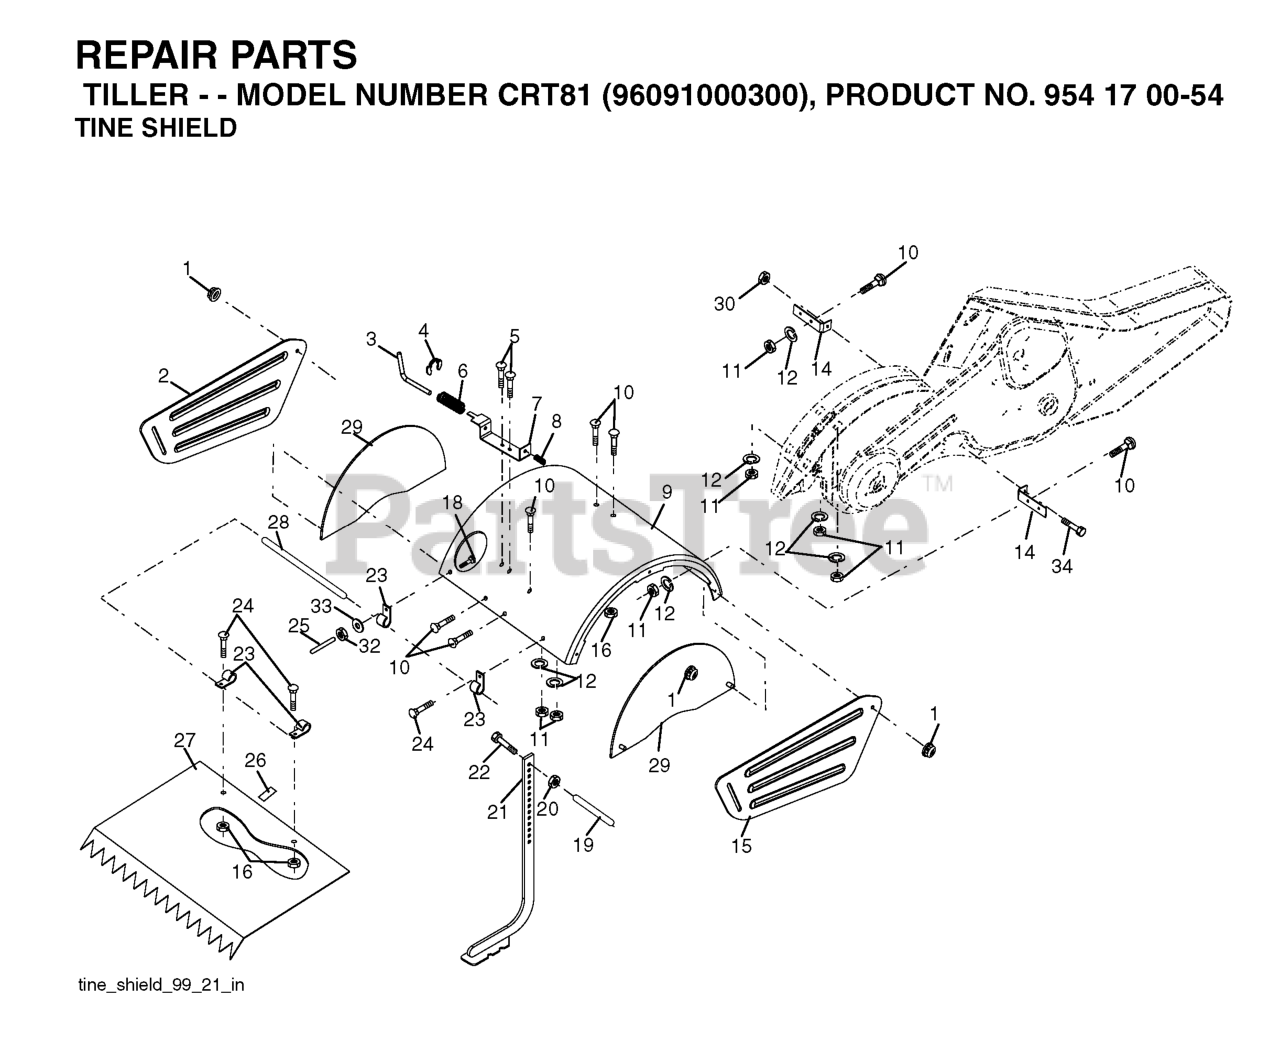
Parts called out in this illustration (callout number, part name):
1	NUT LOCK HEX FLANGE 5/16-18
2	TINE SHIELD
3	STAKE PIN TI
4	RING, KLIP
7	BRACKET.LATCH.STAKE.3.20.BLACK
8	SPRING CRT
9	SHIELD TINE
10	BOLT, RDHD SQNK 5/16-18 X 3/4
12	WASHER.LOCK.HVY.HLCL.SPR.5/16
14	BRACKET.TINE.SHIELD.TILLER
15	SHIELD
16	NUT T
20	NUT.HEX.3/8-16UNC
21	STAKE.ASM.DEPTH
22	BOLT.375-16
25	VINYL CAP TI
26	PAD IDLER TI
27	SHIELD.LEVELING.21".ORANGE
28	PIN, HINGE
29	SHIELD, SIDE
30	LOCKNUT-FLANGE 5/16-18
32	NUT
33	LOCKWASHER
34	Bolt Hex Flanged 5/16-18 Unc x 2
